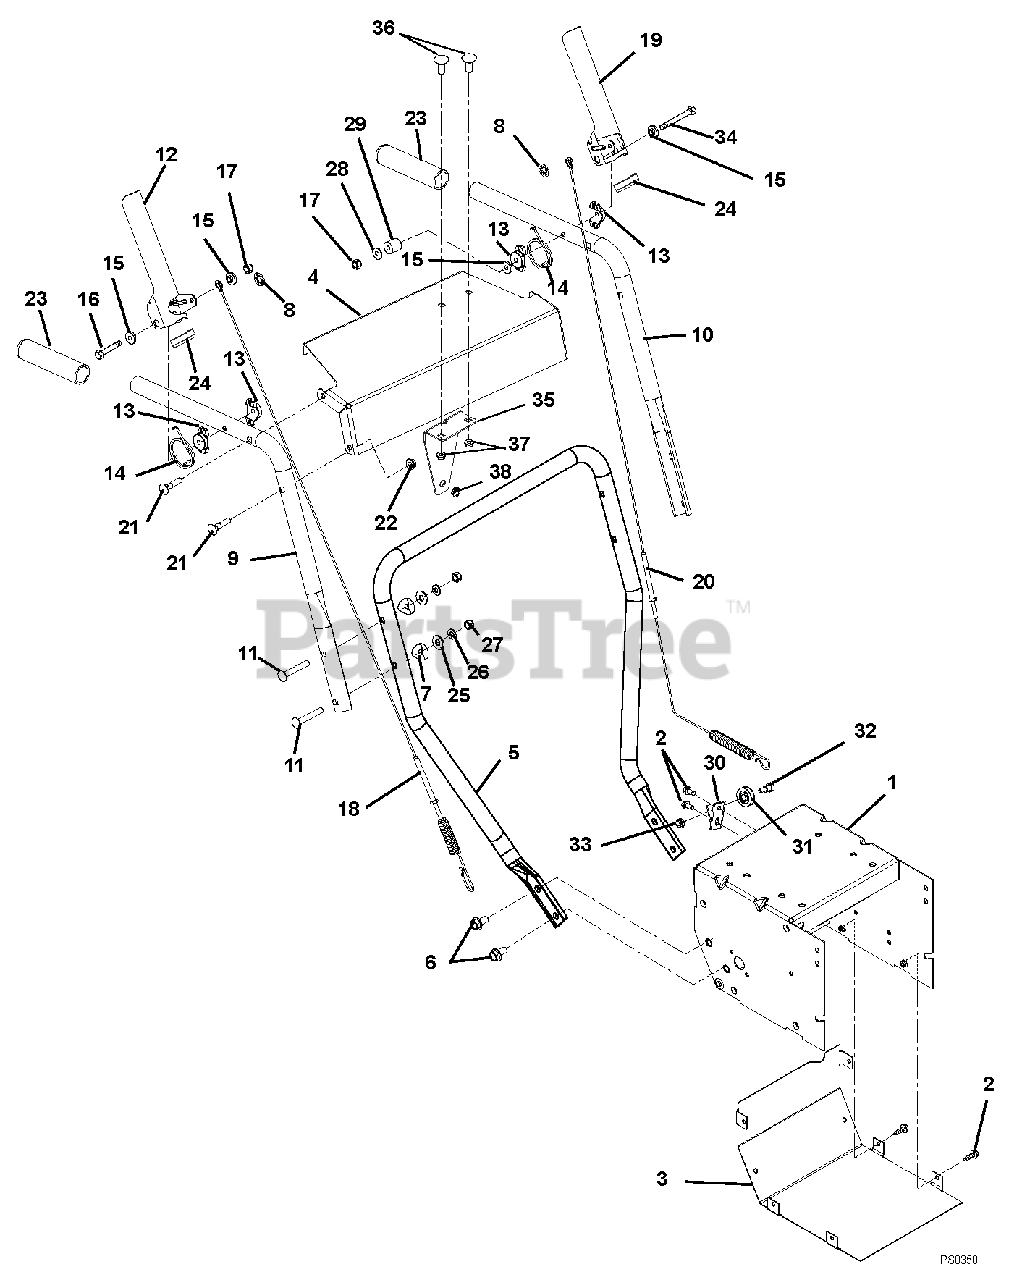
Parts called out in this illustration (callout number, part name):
1	FRAME, WELDMENT
2	SCR-TAP .25-20X.50 HWH TR YWZ
3	COVER, BOTTOM
4	CONTROL PANEL W/DECAL SNO TEK
5	HANDLEBAR, LOWER (SNGLE SPEED)
6	BLT-SERHFWH .38-16X.75 YWZC
7	SPACER, HANDLEBAR
8	RG-RTNG-EXT .250X.010
9	HANDLEBAR, UPPER RH
10	HANDLEBAR, UPPER LH
11	@BLT-RDHDSQNK .31-18X2.25 G5YZ
12	PADDLE, CLUTCH - RH COMPACT
13	SPACER, HANDLEBAR
14	SPRING, TORSION
15	BSHG, FLG .266X.42X.150 PM
16	@BLT-HEX .25-20X2.50 GR5 YWZC
17	NUT-JAM-NYL .250-20 W/INSERTYZ
18	AUGER CABLE, ST520 SINGLE SPD
19	PADDLE, CLUTCH - LH COMPACT
20	CABLE, TRACTION
21	BLT-RDHDXLSQNK .31-18X1.5 G5YZ
22	@NUT-LK-TOP-FLG .31-18 YWZC
23	HANDLE GRIP
24	EDGING, CLUTCH PADDLE - 2.00"
25	@WSHR-FL-STL.38X.875X.083 YWZC
26	@WSHR-LK .31X.078 REG YWZC
27	@NUT-LK-NYL .312-18 YWZC
28	@WSHR-FL-STL.281X.62X.065 YWZC
29	BSHG, SLV .266 X .750 X .750
30	BRACKET, CABLE PULLEY
31	PULLEY, CABLE
32	BOLT, SHLDR-.375X.375X.25-20
33	@NUT-LK-TOP-FLG .25-20 YWZC
34	@BLT-HEX .25-20X3.25 YWZC
35	MOUNT, SNOTK/SNGLSPD CHUT CRNK
36	@BLT-RDHDSQNK .31-18X.75 G5YZ
37	@NUT-LK-TOP-FLG .31-18 YWZC
38	BUSHING, POLYLINER-.38 SNAPIN
